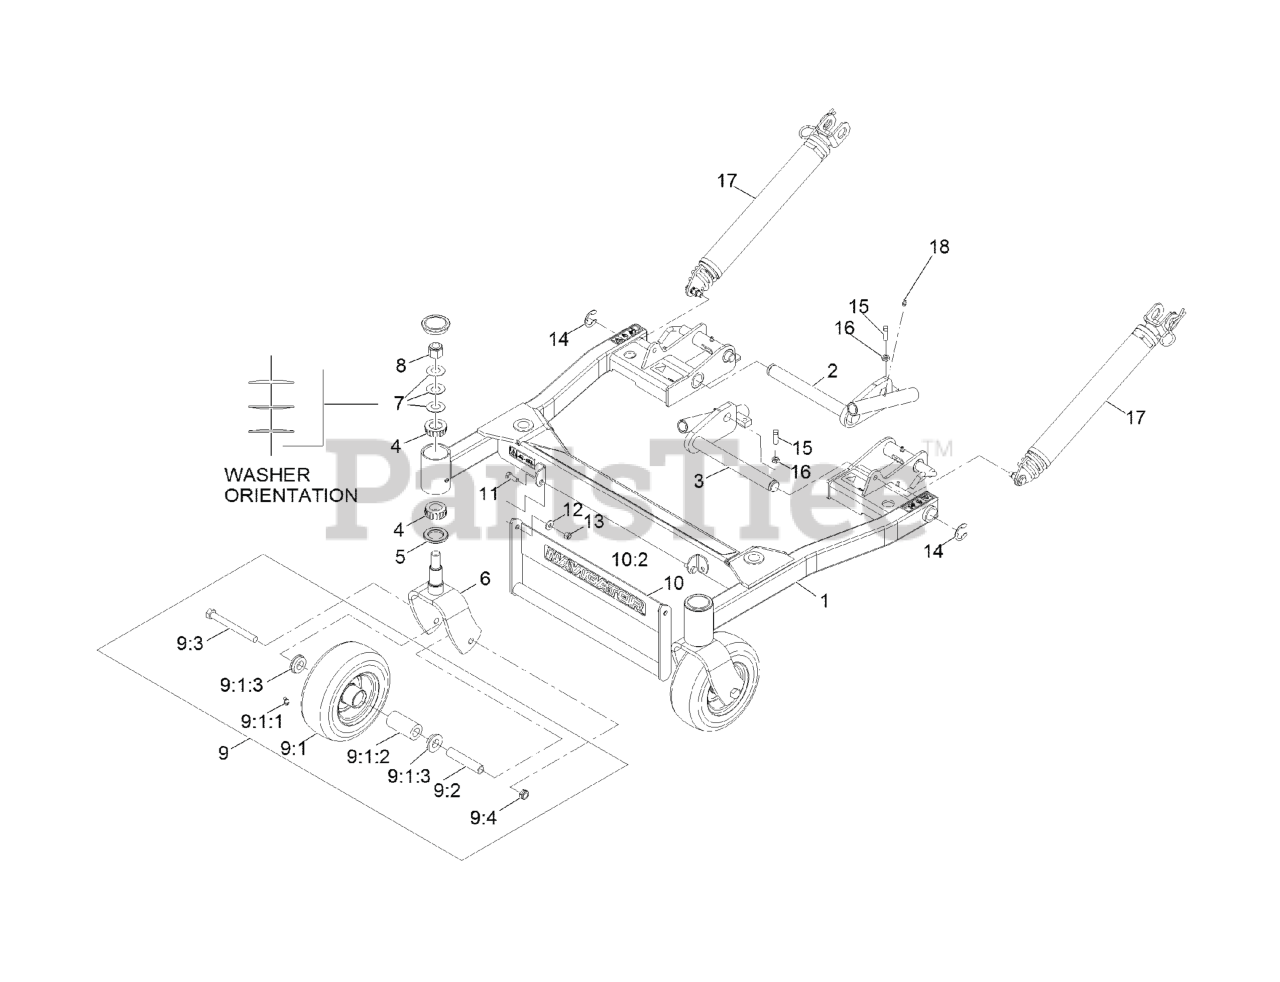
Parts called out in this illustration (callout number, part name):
1	DECK SUPPORT ASM
2	PIVOT-DECK, RH
3	PIVOT-DECK, LH
4	Cone-Bearing Tapered Roller
5	SEAL-GREASE
6	FORK-CASTER
7	WASHER-BELLVILLE
8	NUT-LOCK, NI
9	ASM,FF CASTER WHEEL W/AXL
9:1	ASM,WHEEL,TIRE & BRGS 8X3
9:1:1	FITTING-GREASE
9:1:2	BEARING-ROLLER, STRAIGHT
9:1:3	BUSHING
9:2	SPACER-CASTER, FRONT
9:3	SCREW-HH
9:4	NUT-HEX
10	ASM,DECK LIFT HANDLE W/DE
10:2	Decal-Navigator Logo
11	SCREW-HH
12	WASHER-SPRING
13	NUT-LOCK, NI
14	RING-SNAP
15	SCREW-SET, SQH
16	NUT-JAM
17	LIFT ASSIST SPRING ASM
18	FITTING-GREASE
